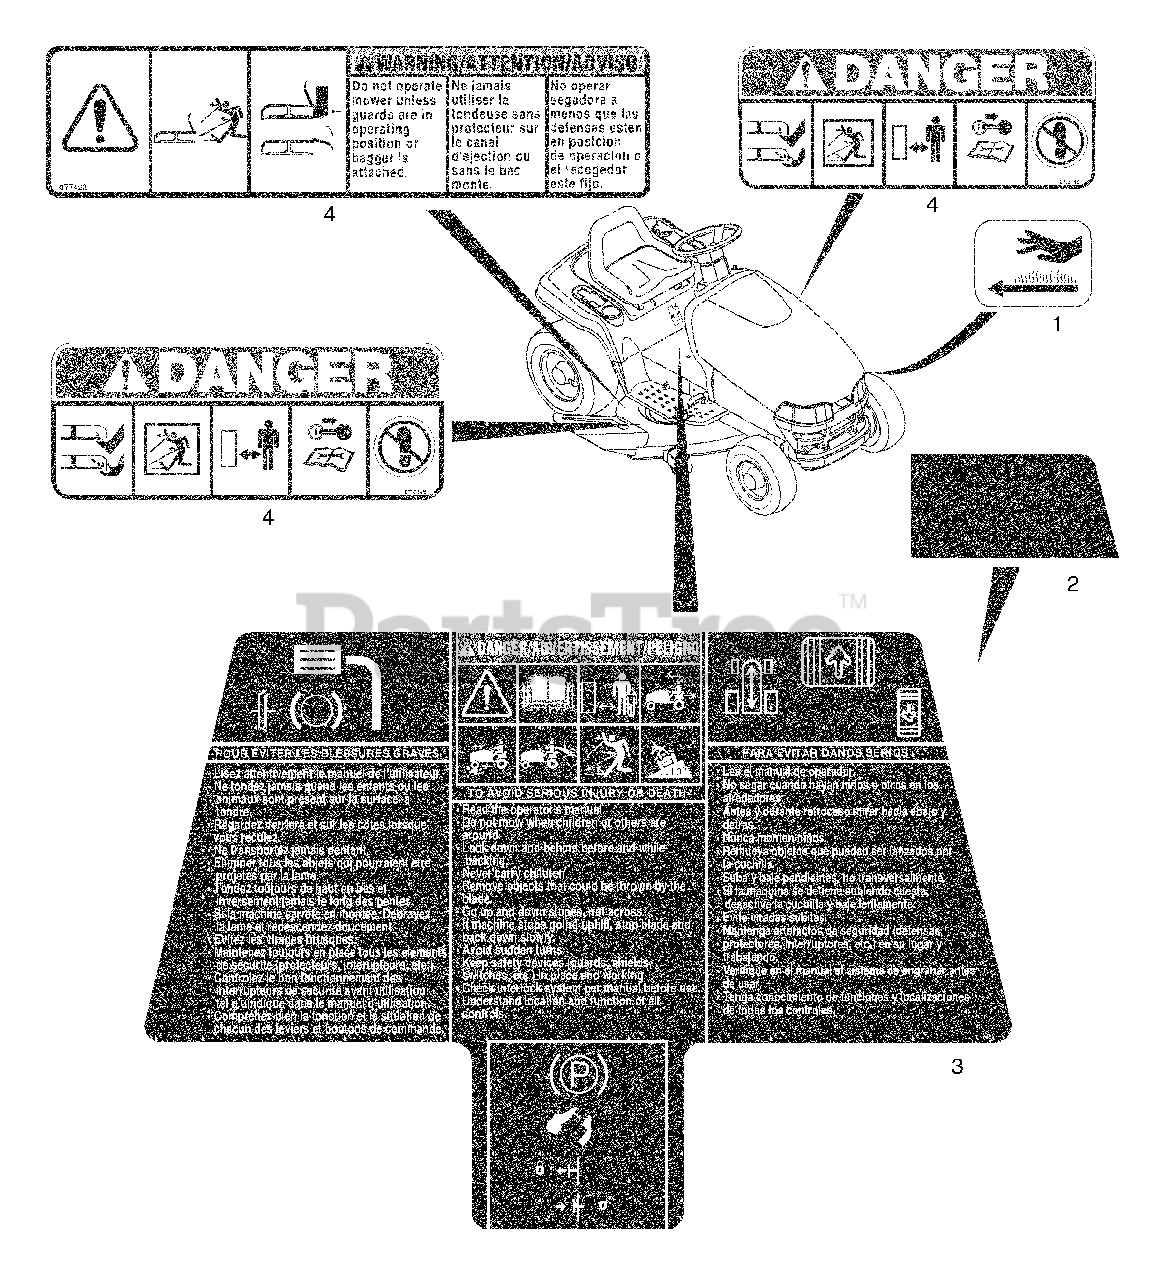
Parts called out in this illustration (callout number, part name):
1	DECAL- HOT SURFACE SYMB.
2	DECAL - COVER
3	DECAL OPERATING INSTRUCTIONS
4	DECAL SET - DECK
